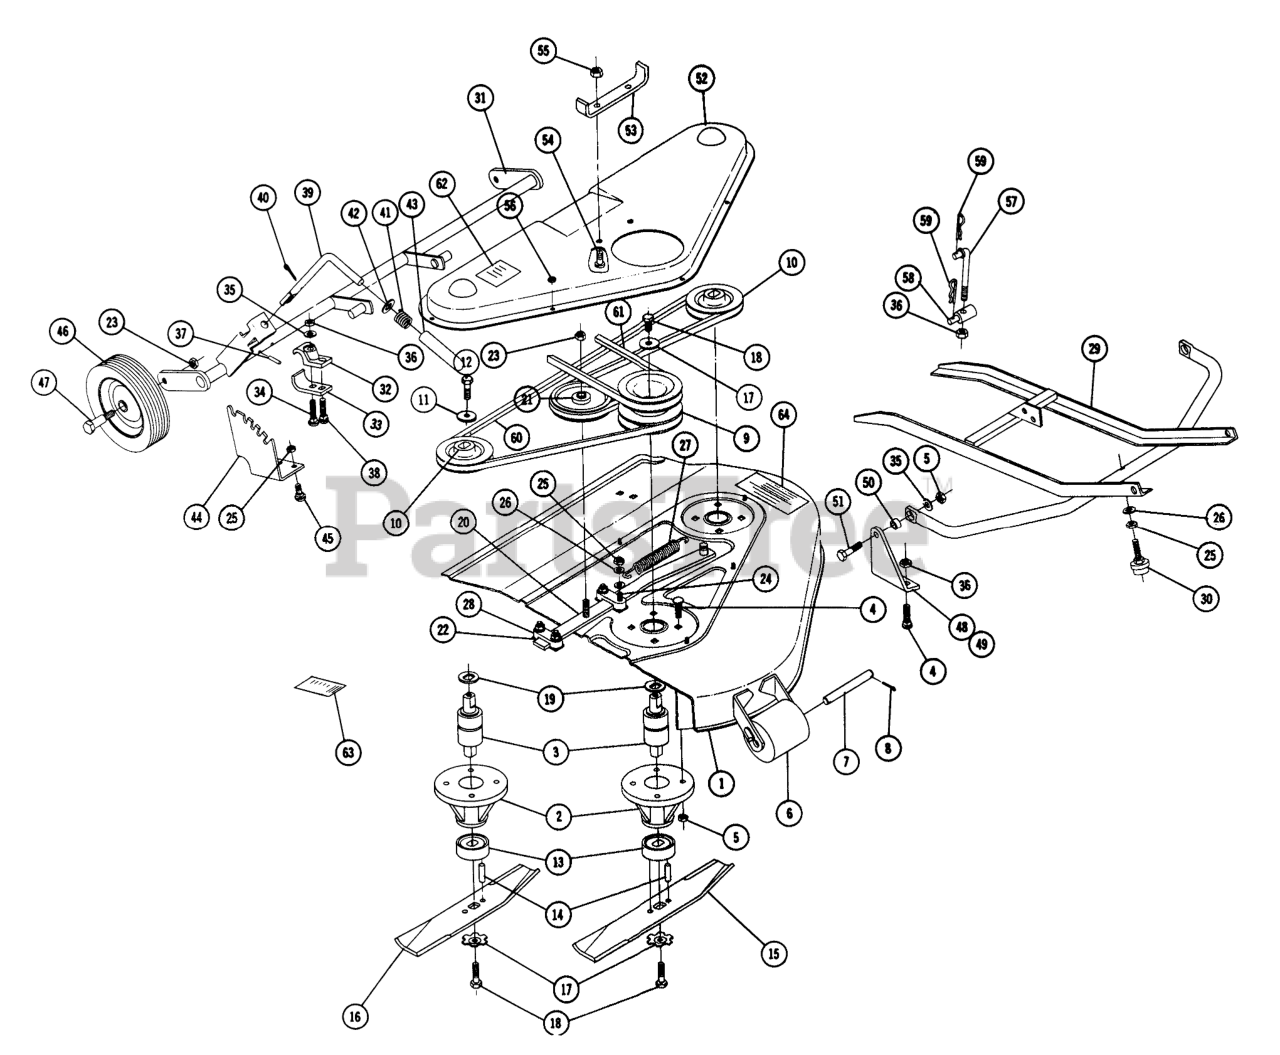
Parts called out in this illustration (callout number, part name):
1	Deck-Mower
2	Housing
3	Bearing-Spindle
4	Bolt 3/8-16 x 1
6	Roller
7	Shaft
8	Cotter Pin
9	Pulley
10	Pulley
11	WASHER
12	Bolt 3/8-16 x 3/4 Hex
13	Cup-Spindle
14	SPIROL ROLL PIN
15	Blade 14"
16	Blade 12"
17	WASHER
18	Bolt 3/8-16 x 7/8
19	WASHER
20	Bar Idler Support
21	Idler Pulley
22	Side Block
23	3/8-16 Jam Nut
24	Bolt-5/16-18 x 1/4
25	Nut-Nylok
26	Washer
27	SPRING R
28	SLIDE
29	Mower Lift
30	Leveler
31	Height Control Bracket
32	Support
33	Clip
34	Bolt-Carriage
35	Washer
36	3/8-16 E.S.
37	Roll Pin
38	Bolt Carriage 3/8-16 x 1
39	FORK
40	Hairpin
41	Spring
42	Washer
43	GRIP
44	Quadrant
45	Bolt 5/16-18 x 5/8 Carriage
46	Wheel
47	BOLT-SHOULDER
48	Bracket L.H.
49	Bracket R.H.
50	SPACER
51	Bolt 3/8-16 x 1
52	Cover
53	Belt Guide
54	Screw-Mach. 1/4-20 x 5/8
55	Nut, 1/4-20
56	HEX NUT 10-32 E.S.
57	Link-Lift
58	Trunnion
59	Hairpin
60	V-BELT
61	BELT DRIVE
62	Decal-Belt Installation
63	Decal-Height Adjustment
64	Decal
